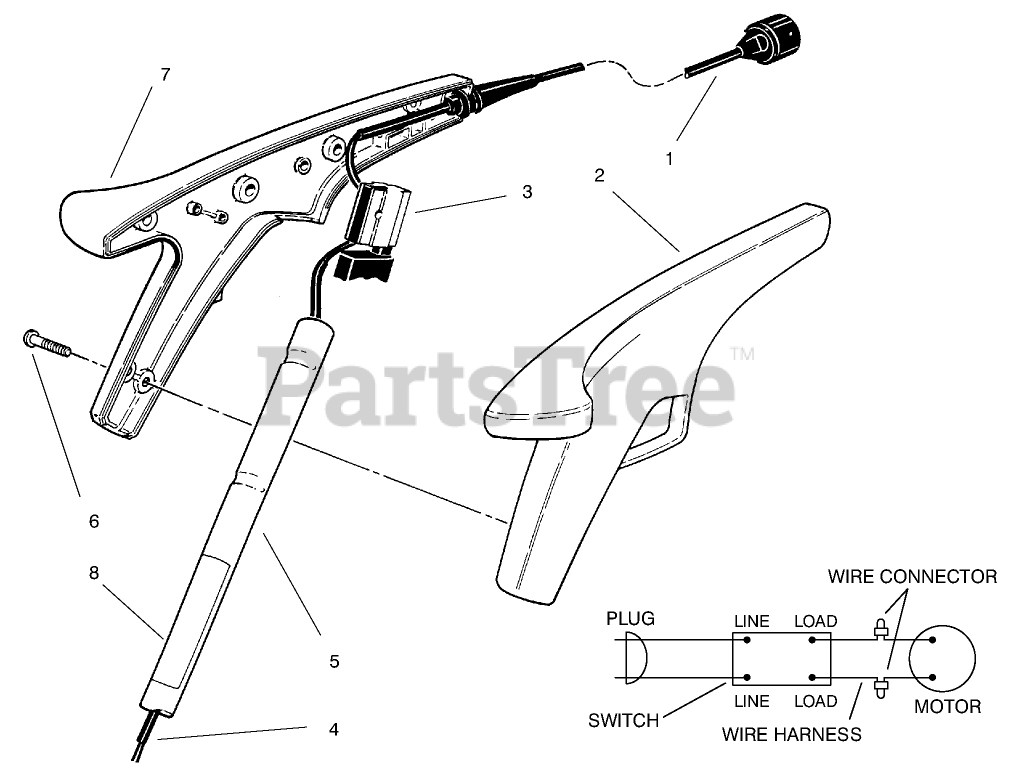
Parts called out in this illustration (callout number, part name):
1	CORD-SUPPLY
2	HAND GRIP - L.H. 8"
3	SWITCH SINGLE SPEED
4	WIRE HARNESS
5	Tube Assy. (Incl. Ref.# 8)
6	SCREW-PPH
7	HAND GRIP - R.H. 8"
8	Decal-Safety
